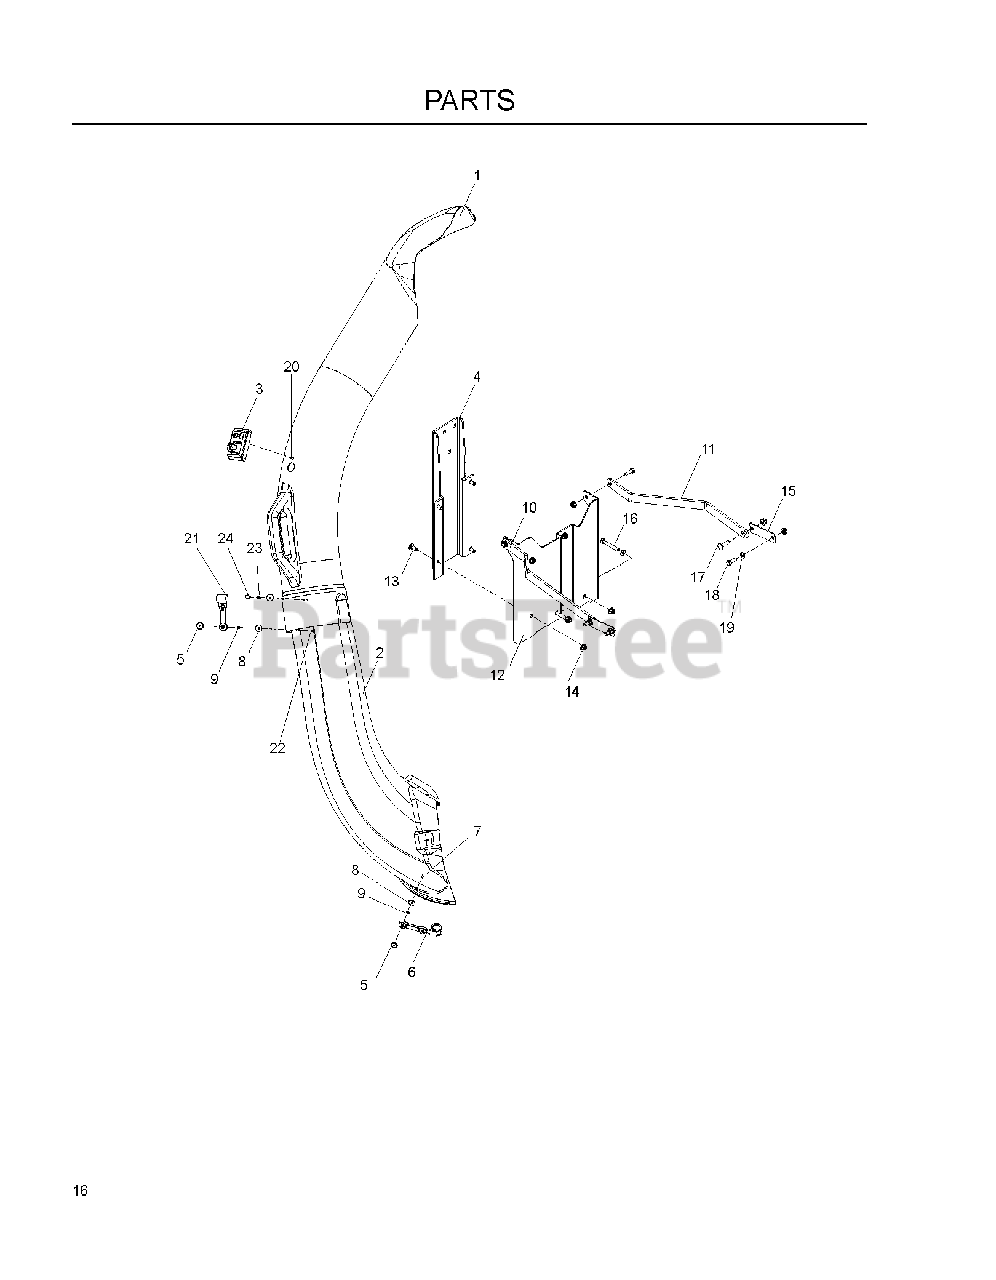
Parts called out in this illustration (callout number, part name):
1	UPPER CHUTE
2	CHUTE.LOWER.LT.46"
3	DUMP BAG INDICATOR
4	BRACKET, COLLECTION BLK
5	NUT 10-24 WELD PLATED
6	LATCH ASSY TBR
7	SCREW #10-24 X 5/8
9	WASHER - 3/16 LOCK ZD
10	STRAP, SUPPORT, RT BLK
11	STRAP, SUPPORT, LT BLK
12	MOUNT, 2 BIN COLLECT, BLK
13	BOLT 5/16C X 3/4" CARRIAGE
14	5/16-18 NYLOC FLANGE NUT
15	REINFORCEMENT PLATE BLK
16	CAPSCREW
17	BOLT, CARRIAGE 5/16X1-1/4
18	HCS 5/16C X 1
19	FLAT WASHER 5/16 SAE
20	SCREW
21	HOOD LATCH
22	SCREW #10-24 X 1-1/8 ZD SPEC
23	BSHG .202X.75 LG SPLIT ZD SPEC
24	NUT 10-24 ACORN ZD
